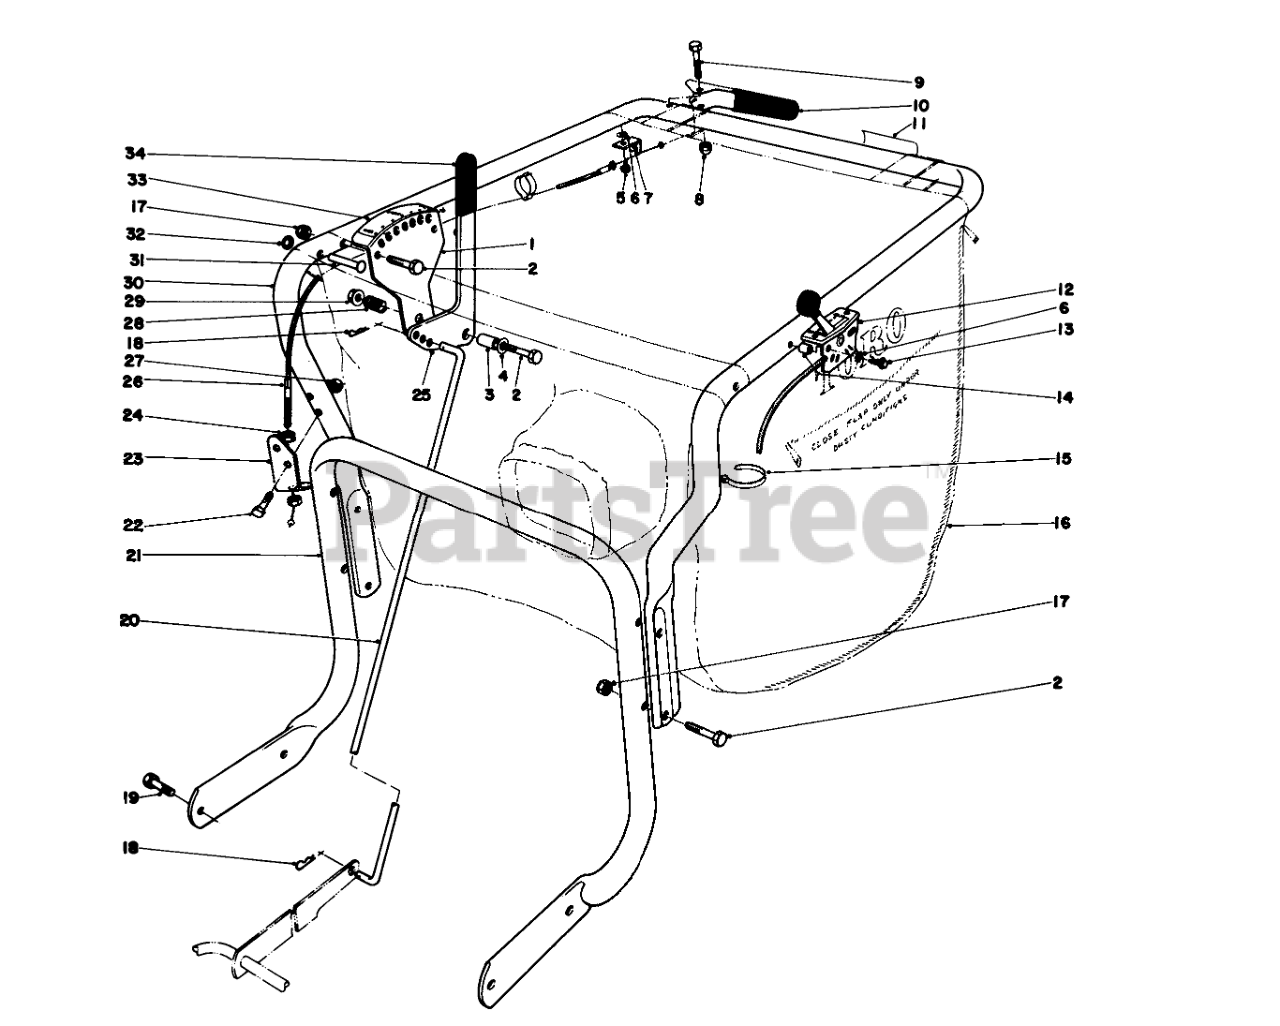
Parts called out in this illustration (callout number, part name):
1	Adjustment Bracket
2	SCREW-HH
3	SPACER
4	WASHER-FLAT
5	SCREW
6	WASHER-LOCK, EXT
7	RETAINING-CLIP
8	NUT-CAP
9	SCREW-HH
10	LEVER W/GRIP
11	TRACTION CONT DECAL
12	THROTTLE CONTROL
13	10-24 X 1 PAN HD SCR
14	SPACER
15	TIE-CABLE
16	Bag-Vacuum
17	NUT-LOCK, CONE
18	PIN-COTTER
19	SCREW-HH
20	HEIGHT ADJ. ROD
21	HANDLE
22	SCREW-HH
23	MOUNT-BOWDEN, LOWER
24	NUT-KEPS
25	Handle-Adjustment
26	FWD ASSY CABLE
27	NUT-LOCK, CONE
28	SPRING-COMPRESSION
29	NUT-HF
30	HANDLE-UPPER, VACUUM
31	RIVET
32	NUT-PUSH IN
33	HT ADJ DECAL
34	GRIP-HANDLE
